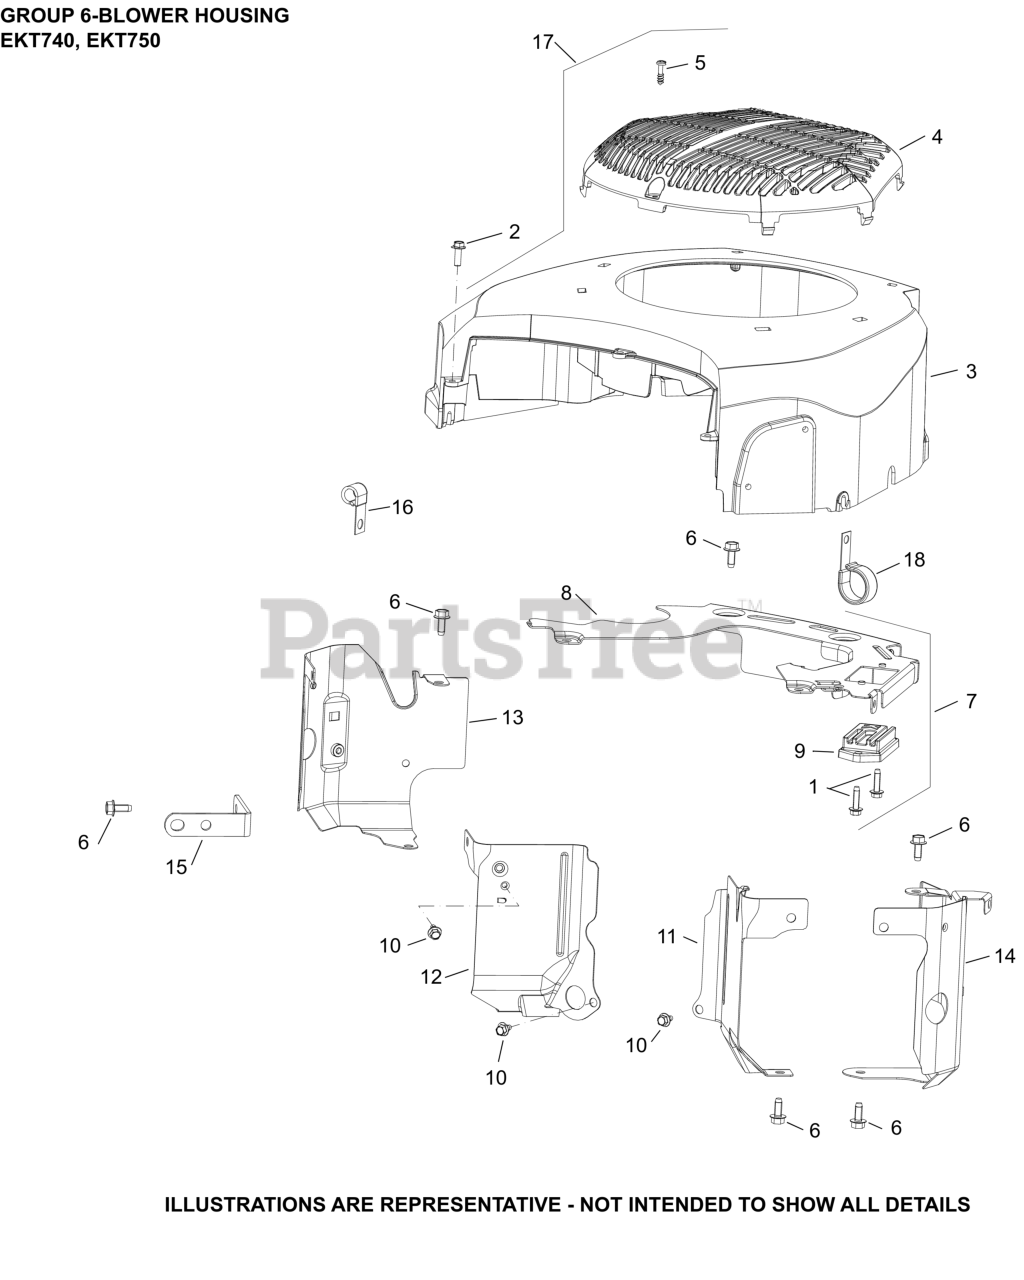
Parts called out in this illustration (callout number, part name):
1	SCREW, THD FRM-USE 25 086 473-S
4	GUARD, FIXED
5	SCREW, M5-2.42 (PT) THREAD
6	SCREW, THREAD FORMING
7	PLATE ASSEMBLY, BACKING (15A)
8	PLATE, BACKING
10	SCREW, THREAD FORMING
12	BAFFLE, VALLEY #1
13	BAFFLE, EFI RIGHT BARREL
14	BAFFLE, EFI LEFT BARREL
15	STRAP, LIFTING
16	CLIP, CABLE (KM)
17	KIT, BLOWER HOUSING
NI	SCREW, HI-LOW
NI	REG/RECT (15AMP,HW,OVP)-(#2540346S)
NI	BAFFLE, VALLEY #2
